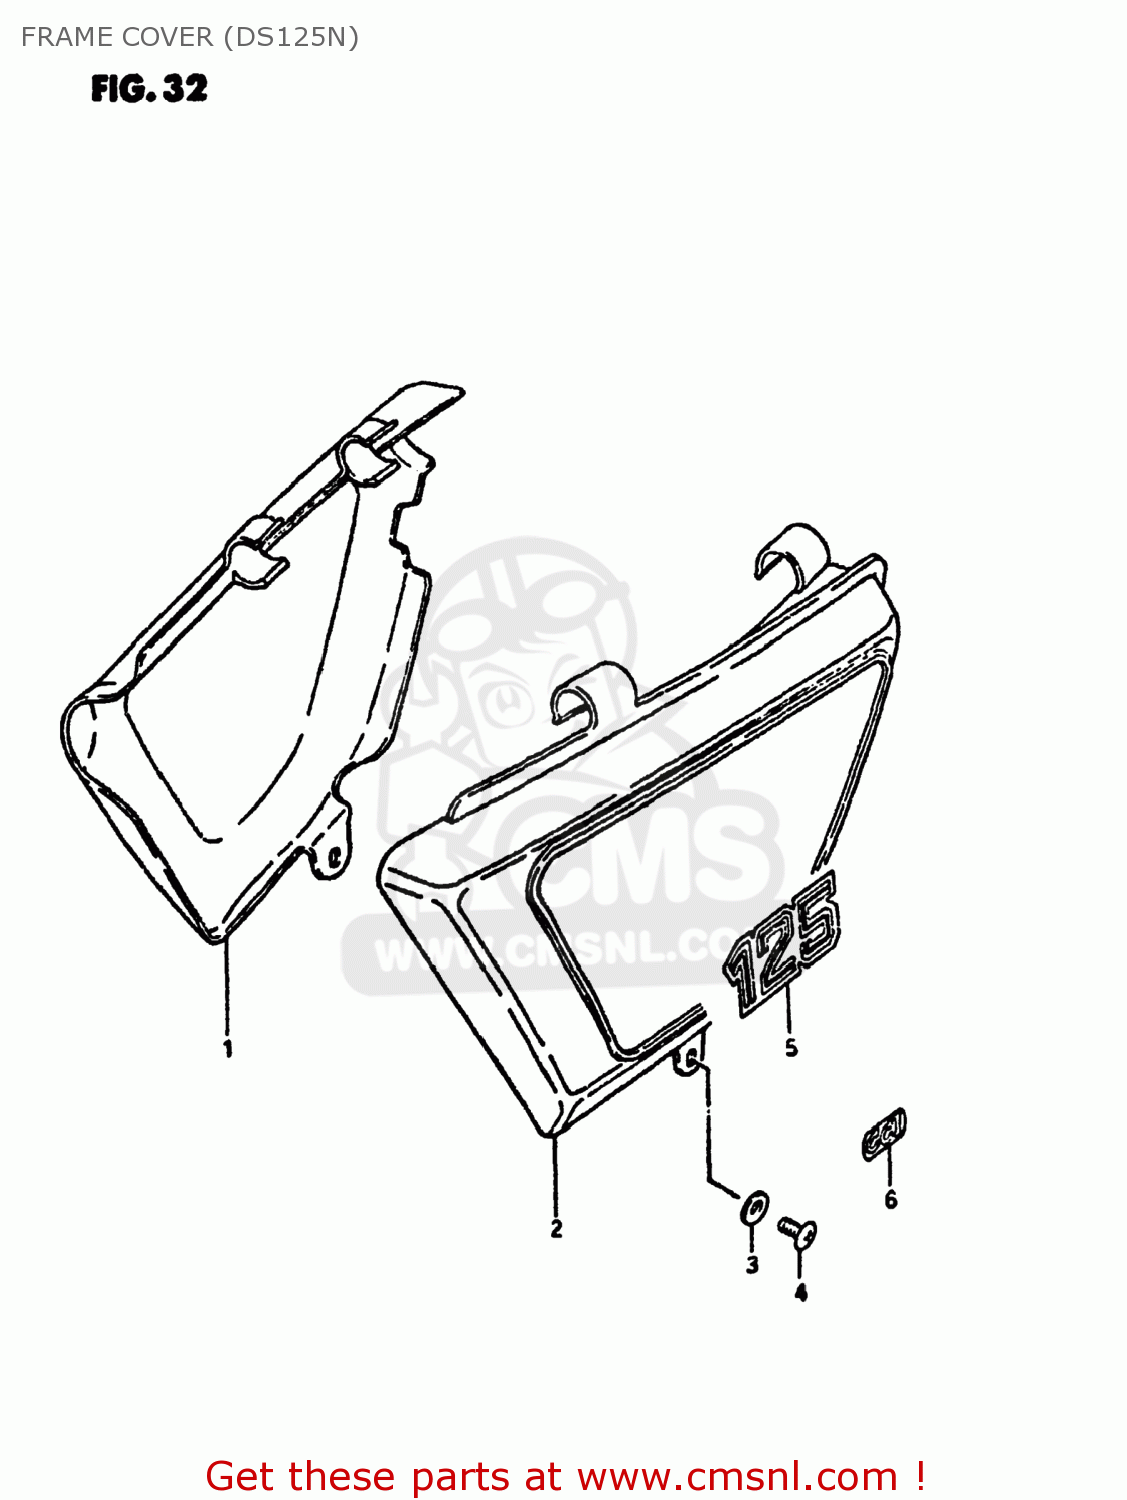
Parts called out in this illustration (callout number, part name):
1	COVER,FRAME,RIGHT
2	COVER,FRAME,LEFT
3	WASHER
4	SCREW 6X12
5	EMBLEM
6	EMBLEM,CCIS
